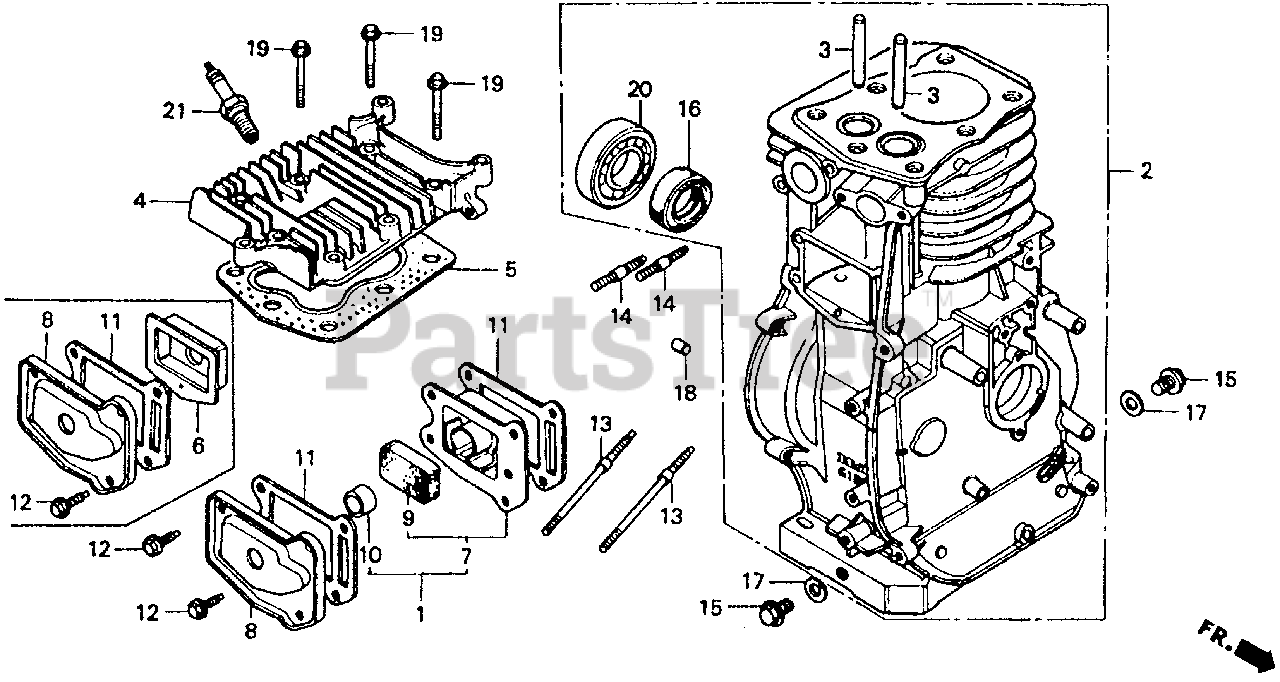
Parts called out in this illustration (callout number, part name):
1	CASE KIT, BREATHER
2	CYLINDER ASSY.
3	GUIDE, VALVE (OS)
4	CYLINDER HEAD
5	GASKET, CYLINDER HEAD
6	CASE, BREATHER
7	CASE, BREATHER
8	COVER, TAPPET ROOM
9	FILTER, BREATHER
10	SEAL, BREATHER
11	GASKET, TAPPET COVER
12	BOLT, FLANGE (6X12) (CT200)
13	BOLT, STUD (6X96)
14	BOLT, STUD (8X35)
15	BOLT, DRAIN PLUG
16	OIL SEAL (25X41X6)
17	WASHER, DRAIN PLUG (12MM)
18	PIN A, DOWEL (8X14)
19	BOLT, FLANGE (8X45)
20	BEARING, RADIAL BALL (6205)
21	SPARK PLUG (B-4H)
21	SPARK PLUG (W14F-U) (DENSO)
21	SPARK PLUG (W14FR-U) (DENSO)
21	SPARK PLUG (BP-4HS-10) (NGK)
21	SPARK PLUG (BPR-4HS-10) (NGK)
21	SPARK PLUG (BPR4HS-10) (NGK)
21	SPARK PLUG (BP4HS-10) (NGK)
21	SPARK PLUG (W14FP-UL10) (DENSO)
21	SPARK PLUG (W14FPR-UL10) (DENSO)
21	SPARK PLUG (B6HS) (NGK)
21	SPARK PLUG (BR6HS) (NGK)
21	SPARK PLUG (W20FS-U) (DENSO)
21	SPARK PLUG (W20FPR-U10) (DENSO)
